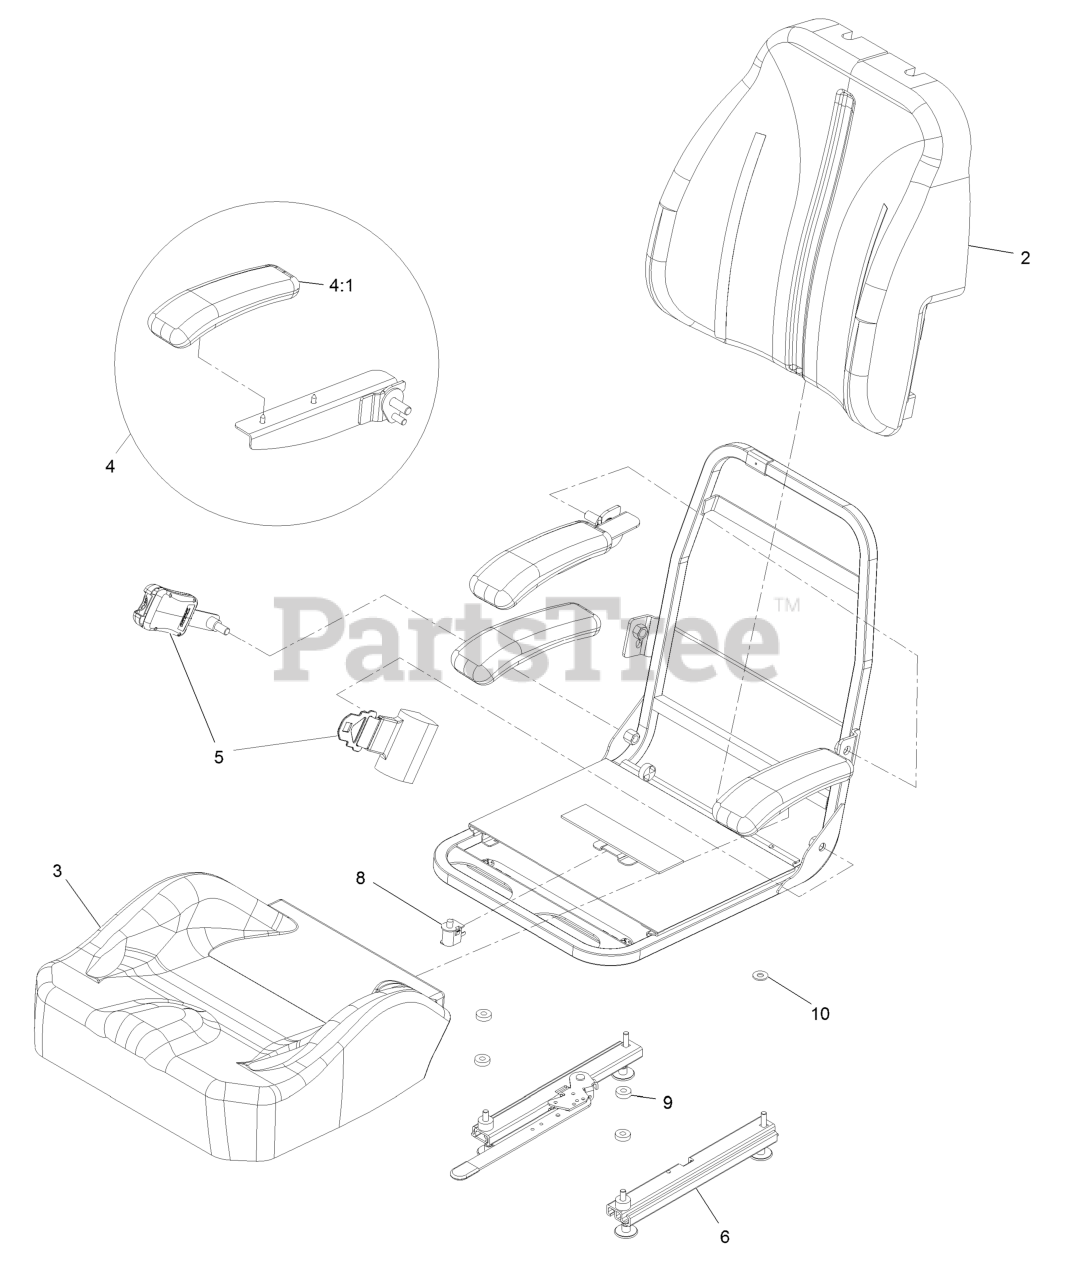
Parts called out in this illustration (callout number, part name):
2	Cover-Seat Back
3	Cover-Seat Cushion
4	Armrest Kit
4:1	Cushion-Rest, Arm
5	Kit-Seat Belt Service
6	ASM-Seat Track, Svc
9	Spacer-Pin, Mounting
10	Washer-5/16 Std
